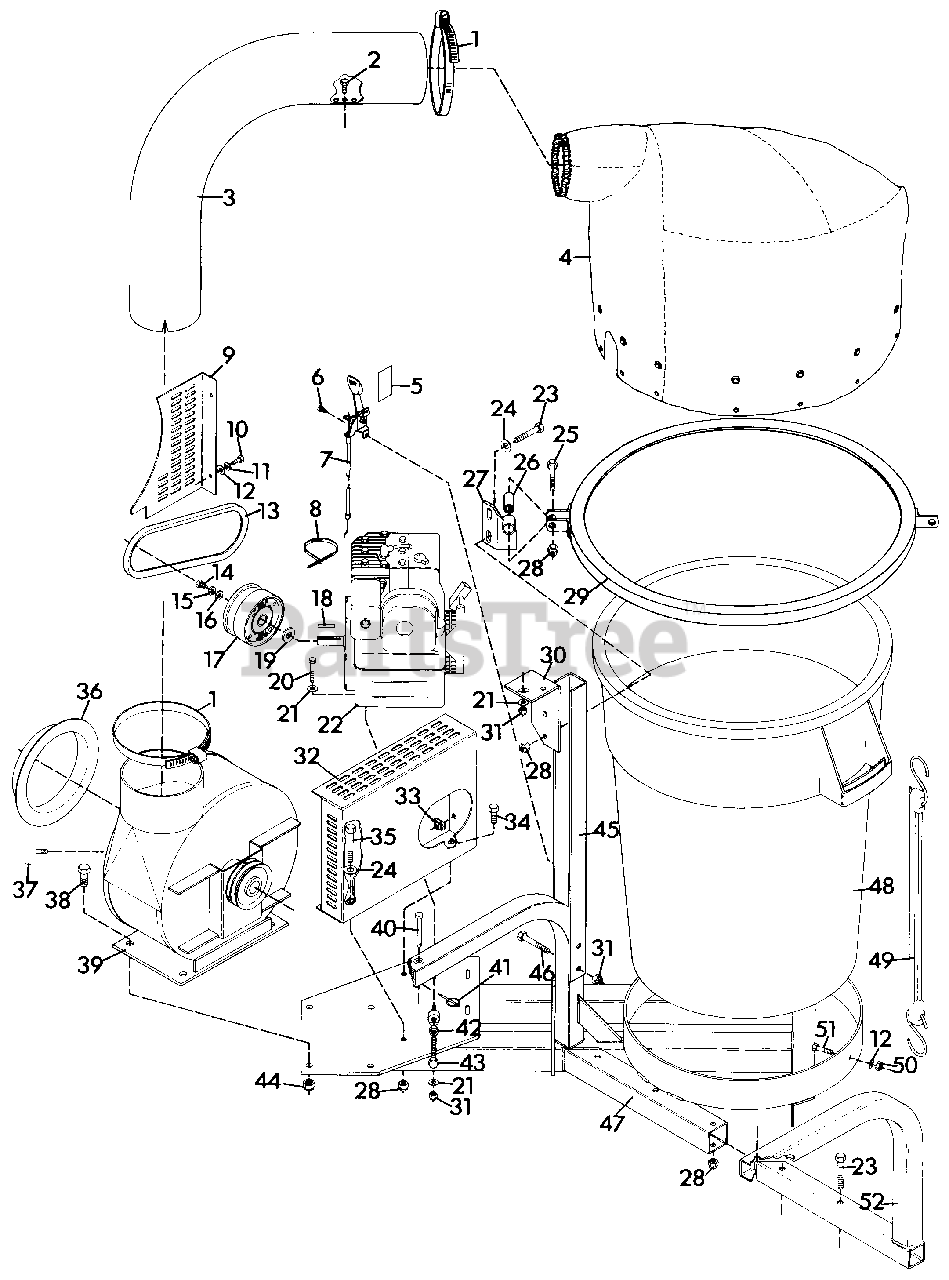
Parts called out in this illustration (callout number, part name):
1	CLAMP
2	BOLT, HEX 5/16-18X1.00
3	TUBE, BLOWER TO CAN
4	COVER, GRASS CATCHER
5	DECAL, THROTTLE
6	SCREW, TAPPING 10-24X.50
7	LEVER, THROTTLE CONTROL
8	TIE, CABLE
9	COVER, GUARD
10	BOLT, HEX 1/4-20X.75
11	WASHER, LOCK 1/4 REG.
12	WASHER, FLAT .281X.625X.065
13	V-BELT
14	BOLT, HEX 5/16-24X.75
15	WASHER, LOCK 5/16 REG.
16	WASHER, FLAT .313X.875X.065
17	CLUTCH
18	KEY, HUB .187X1.500
19	RACE, BEARING THRUST .060
20	BOLT, HEX 5/16-18X1.75
21	WASHER, FLAT .344X.688X.065
23	BOLT, HEX 3/8-16X2.50
24	WASHER, FLAT .406X.812X.065
25	BOLT, HEX 3/8-16X2.00
26	BUSHING, .385X.625X1.00
27	WELDMENT, PIVOT BRACKET
28	NUT, LOCK 3/8-16
29	WELDMENT, RING
30	BRACKET, TUBE
31	NUT, LOCK 5/16-18
32	GUARD
33	NUT, RETAINER
34	BOLT, HEX 3/8-16X.875
35	BOLT, HEX 3/8-16X2.75
36	ADAPTER, HOSE
37	HANDLE, LOCKING
38	BOLT, HEX 1/2-13X1.25
40	PIN, CLEVIS 3/8X2.62
41	PIN, KLIK
42	NUT, HEX 3/8-16
43	BOLT, HEX SPEC. 3/8-16X3.00
44	NUT, LOCK 1/2-13
45	UPRIGHT
46	BOLT, HEX 5/16-18X2.25
47	WELDMENT, BLOWER FRAME
48	CAN, GRASS
49	STRAP, HOLD DOWN
50	NUT, LOCK 1/4-20
51	BOLT, HEX 1/4-20X1.25
52	WELDMENT, HANGER TUBE
